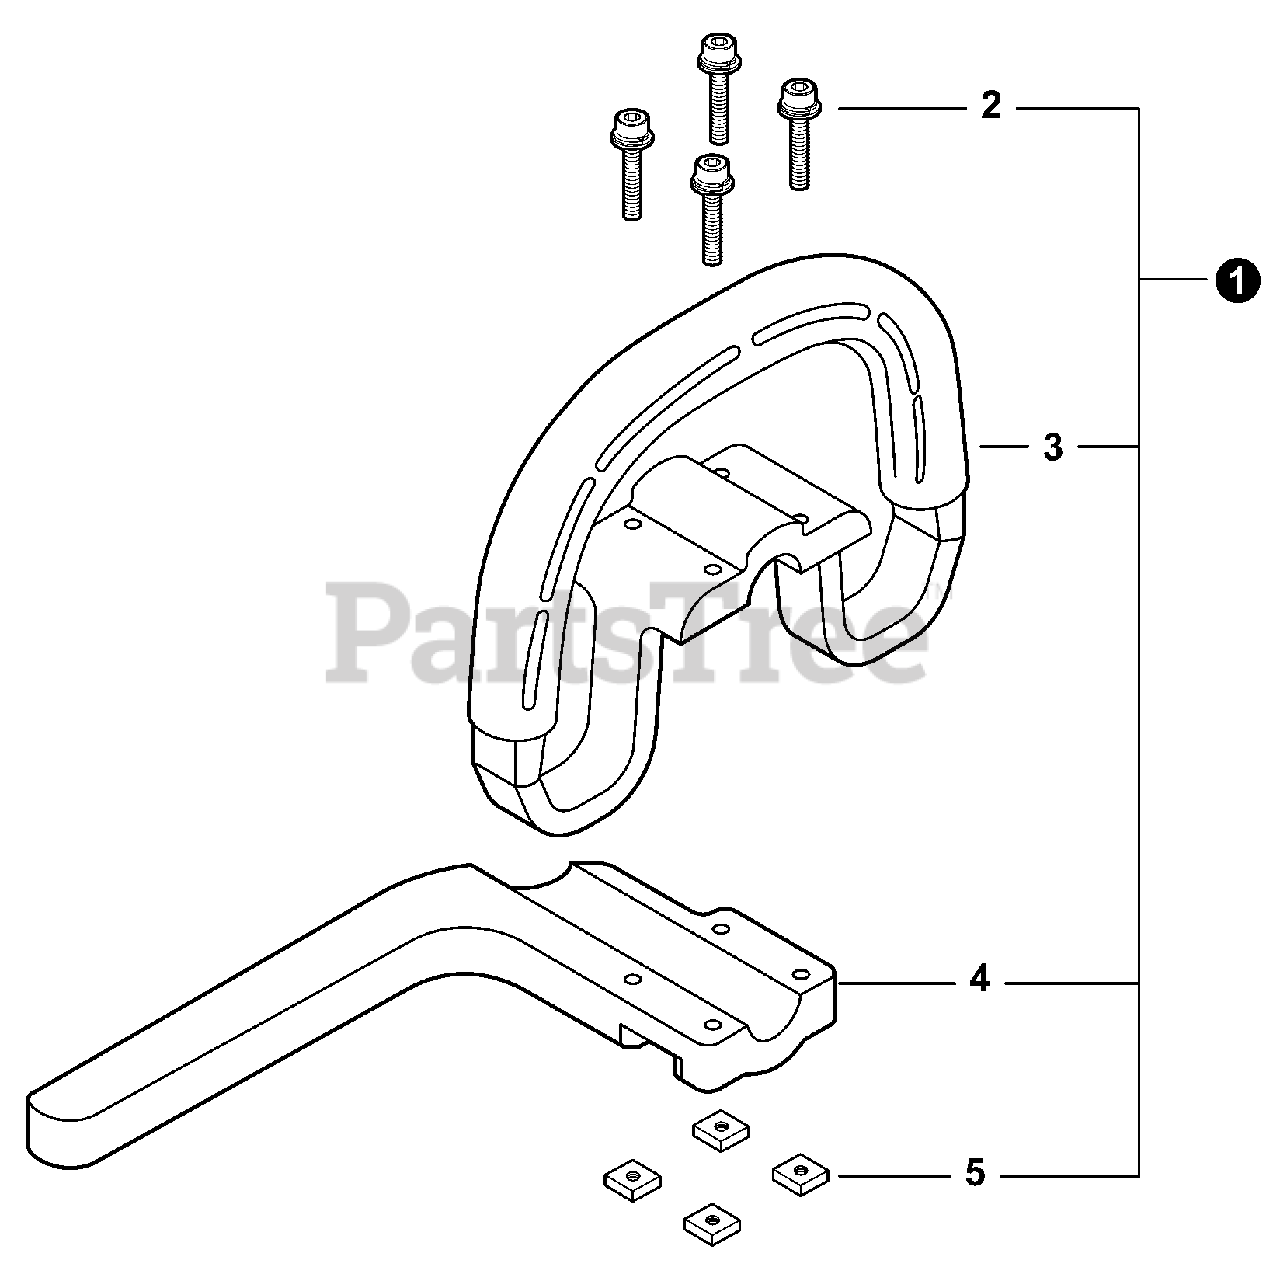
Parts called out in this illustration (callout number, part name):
1	HANDLE ASSY
2	BOLT M5×35
3	HANDLE, SUPPORT
4	BAR, BARRIER
